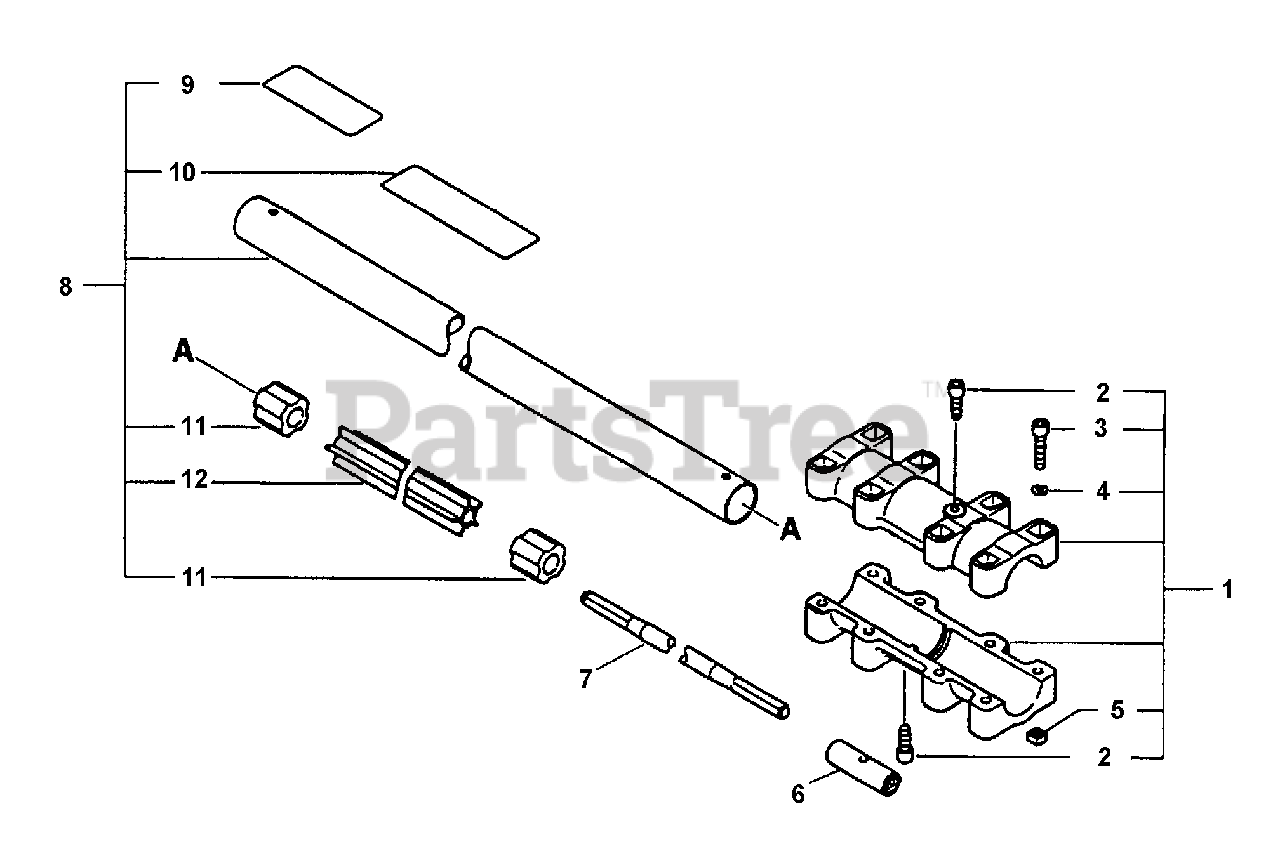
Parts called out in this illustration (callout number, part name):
1	CLAMP, MAIN PIPE
2	SCREW - 5X12
3	SCREW - 5X25
4	LOCKWASHER - 5
5	NUT - 5 -- SQUARE
6	CONNECTOR, SHAFT
7	DRIVESHAFT - FLEXIBLE
8	MAIN PIPE ASSY
9	LABEL - CAUTION
10	LABEL - CAUTION
12	LINER - FLEXIBLE
